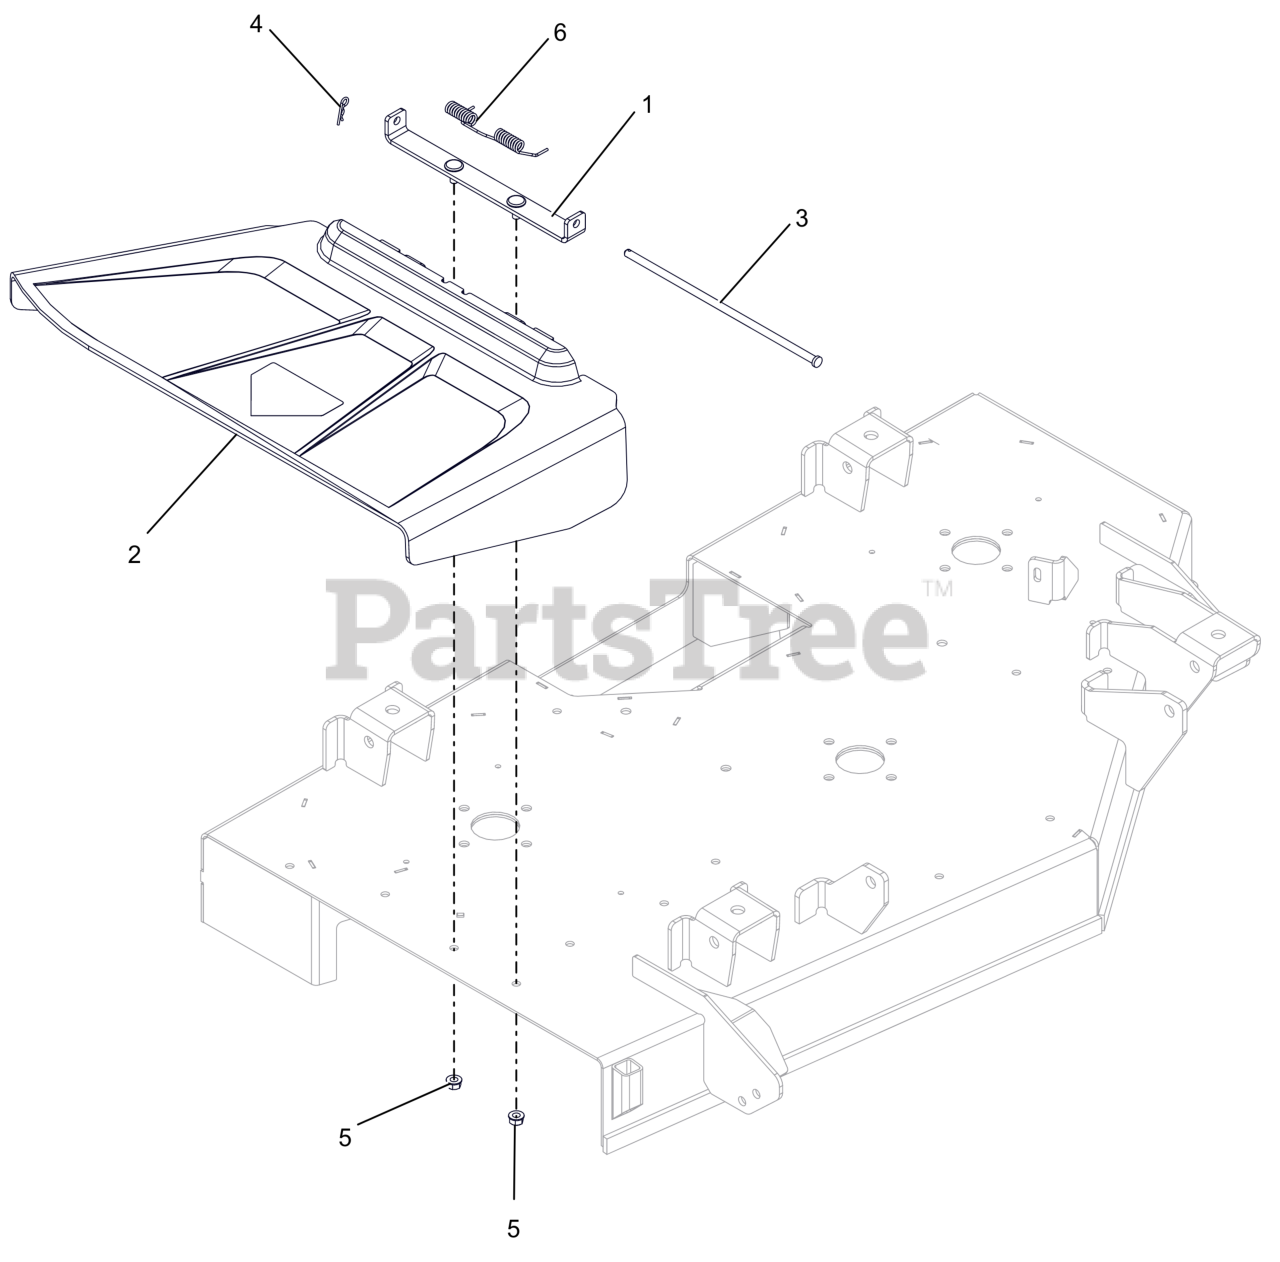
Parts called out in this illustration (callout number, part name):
2	CHUTE, SIDE DISCHARGE
3	PIN, 5/16 X 10.5
4	PIN, HAIR #213 .08X1.19 ZCC
5	NUT-LK-TOP-FLG .312-18 GF ZCC
6	SPRING-TORSION
